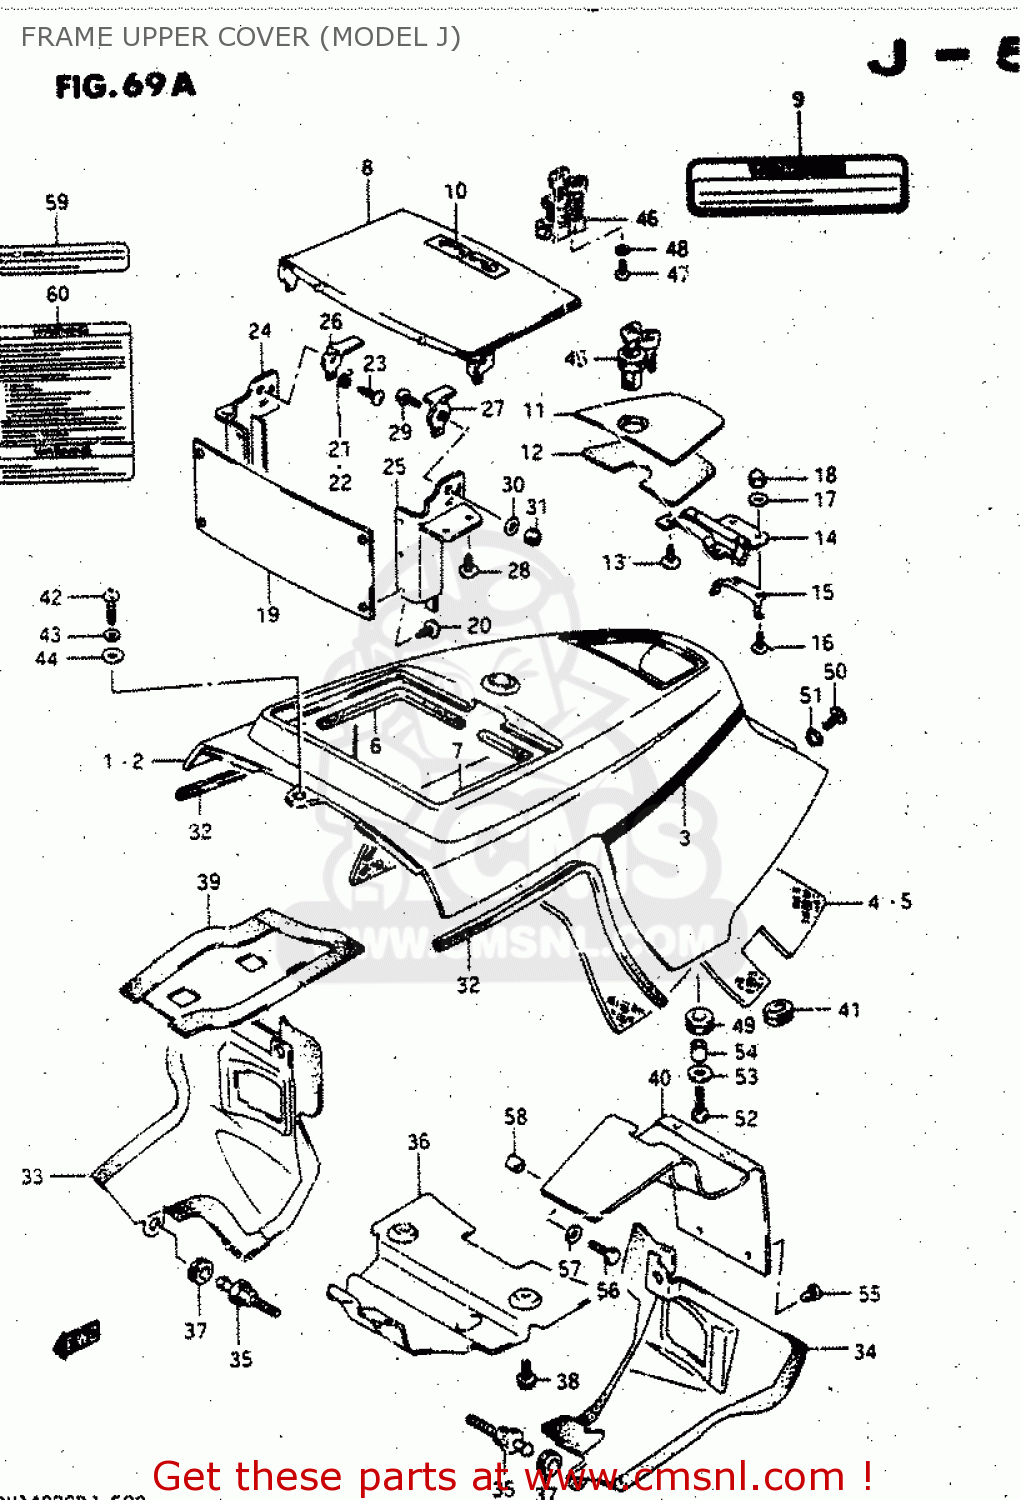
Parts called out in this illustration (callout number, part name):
1	COVER ASSEMBLY,FRAME,UPPER
2	COVER ASSEMBLY,FRAME,UPPER
3	TAPE SET,UPPER COVER SIDE
4	CUSHION,FRAME COVER,UPPER
5	CUSHION,FRAME COVER,UPPER
6	CUSHION,AUDIO LID SIDE
7	CUSHION,AUDIO LID SIDE
8	COVER ASSEMBLY,FRAME,UPPER
9	LABEL (WARNING COVER CO
10	EMBLEM
11	LID,FUEL
12	CUSHION,FUEL LID (NA)
13	SCREW 5X8
14	HINGE,FUEL LID
15	SPRING,FUEL LID HINGE
16	SCREW
17	WASHER
18	NUT
19	HOLDER,AUDIO LID
20	SCREW
21	SPRING
22	SPRING
23	SCREW
24	RAIL,RIGHT
25	RAIL,LEFT
26	RAIL PIECE,RIGHT
27	RAIL PIECE,LEFT
28	SCREW, RAIL
29	SCREW
30	WASHER
31	NUT 8MM
32	MOLDING,COVER FRAME,UPPER
33	COVER,INNER,RIGHT
34	COVER,INNER,LEFT
35	BOSS,FRAME COVER
36	COVER COMP,INNER
37	CUSHION
38	BOLT
39	COVER COMP,UPPER,RIGHT
40	COVER COMP,UPPER,LEFT
41	GROMMET
42	SCREW, 6X20
43	LOCK WASHER
44	WASHER (6.5X18X1.6)
45	LOCK SET,TOOL HOLDER
46	LOCK ASSEMBLY,AUDIO LID
47	SCREW
48	LOCK WASHER
49	CUSHION
50	SCREW
51	WASHER
52	BOLT
53	WASHER, LOWER
54	SPACER (6.1X8X9.5)
55	RIVET
56	BOLT
57	WASHER(6.5X16X1.2)
58	SPACER (6.5X12X8)
59	LABEL (WARNING AUDIO BO
60	LABEL (WARNING)
